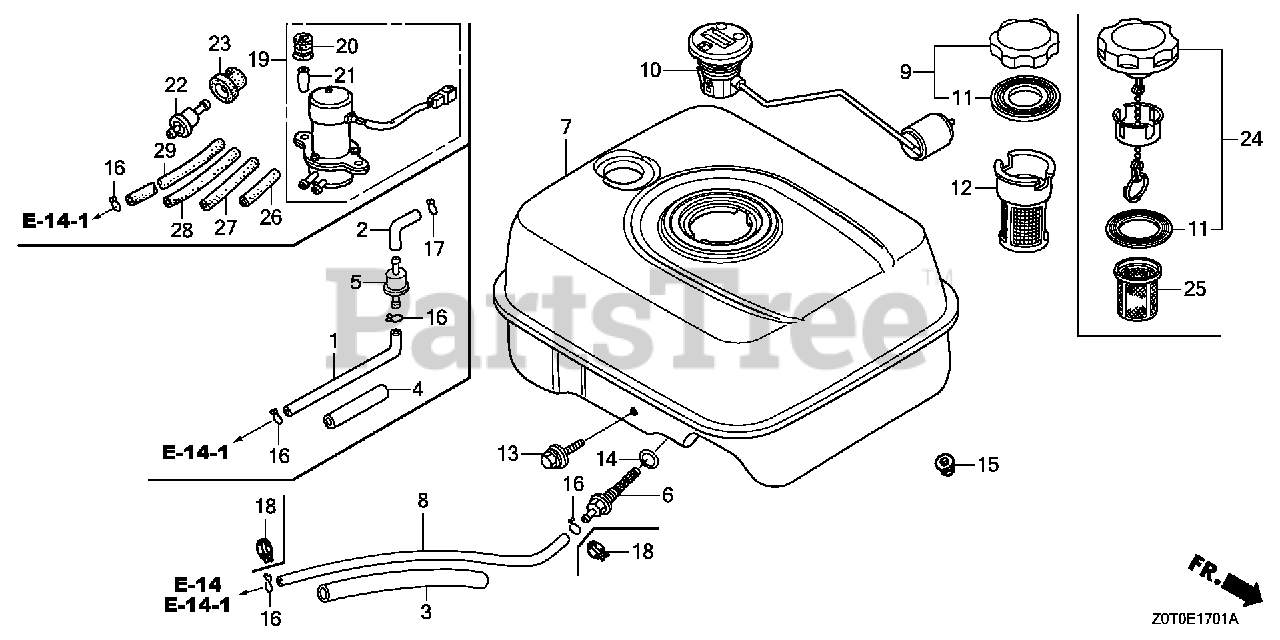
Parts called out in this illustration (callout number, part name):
3	RUBBER, SUPPORTER (107MM)
6	JOINT, FUEL TANK
7	TANK, FUEL *NH31* (MCKINLEY WHITE)
7	TANK, FUEL *NH1* (BLACK)
8	TUBE, FUEL (4.5X145) (FKM)
11	GASKET, FUEL FILLER CAP (39X62X3) (RADICON)
13	BOLT, FLANGE (6X29)
14	O-RING (13.5X1.5) (ARAI)
14	O-RING (14MM) (NOK)
15	NUT, FLANGE (6MM)
18	CLAMP, TUBE (D8)
24	CAP, FUEL FILLER
